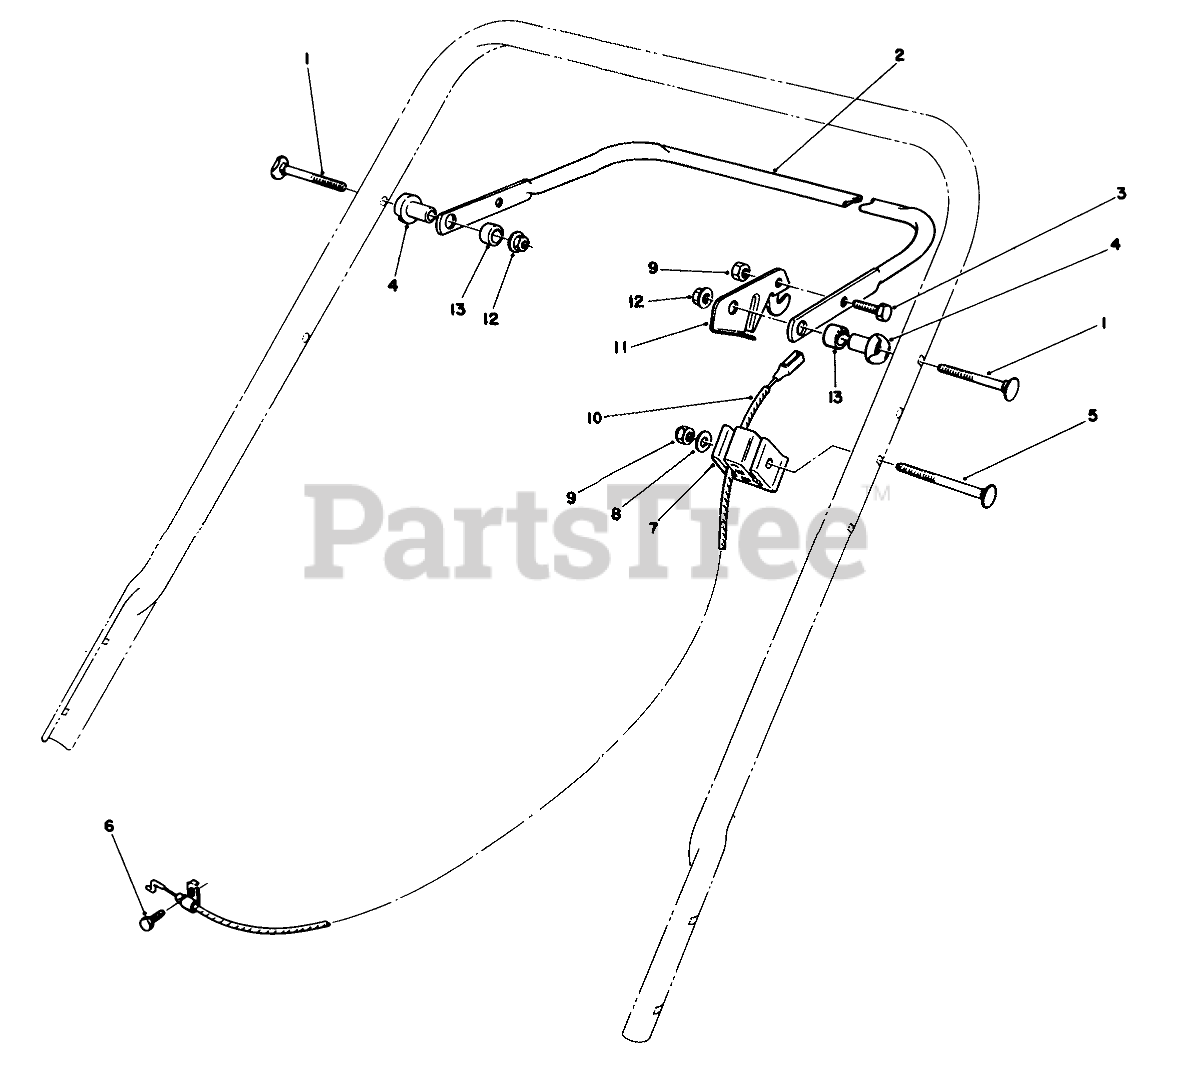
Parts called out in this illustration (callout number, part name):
1	5/16-18 X 2 HNDLE SCREW
2	CONTROL BAR PROMO
2	Bar-Control
3	SCREW-HH
4	SPACER-SUPPORT
5	HANDLE SCREW
6	SCREW-HH
7	SUPPORT-CABLE
8	WASHER-FLAT
9	NUT-LOCK, NI
10	BRAKE CABLE
11	Lever-Control
12	NUT-LOCK, NI
13	SPACER-NYLON
